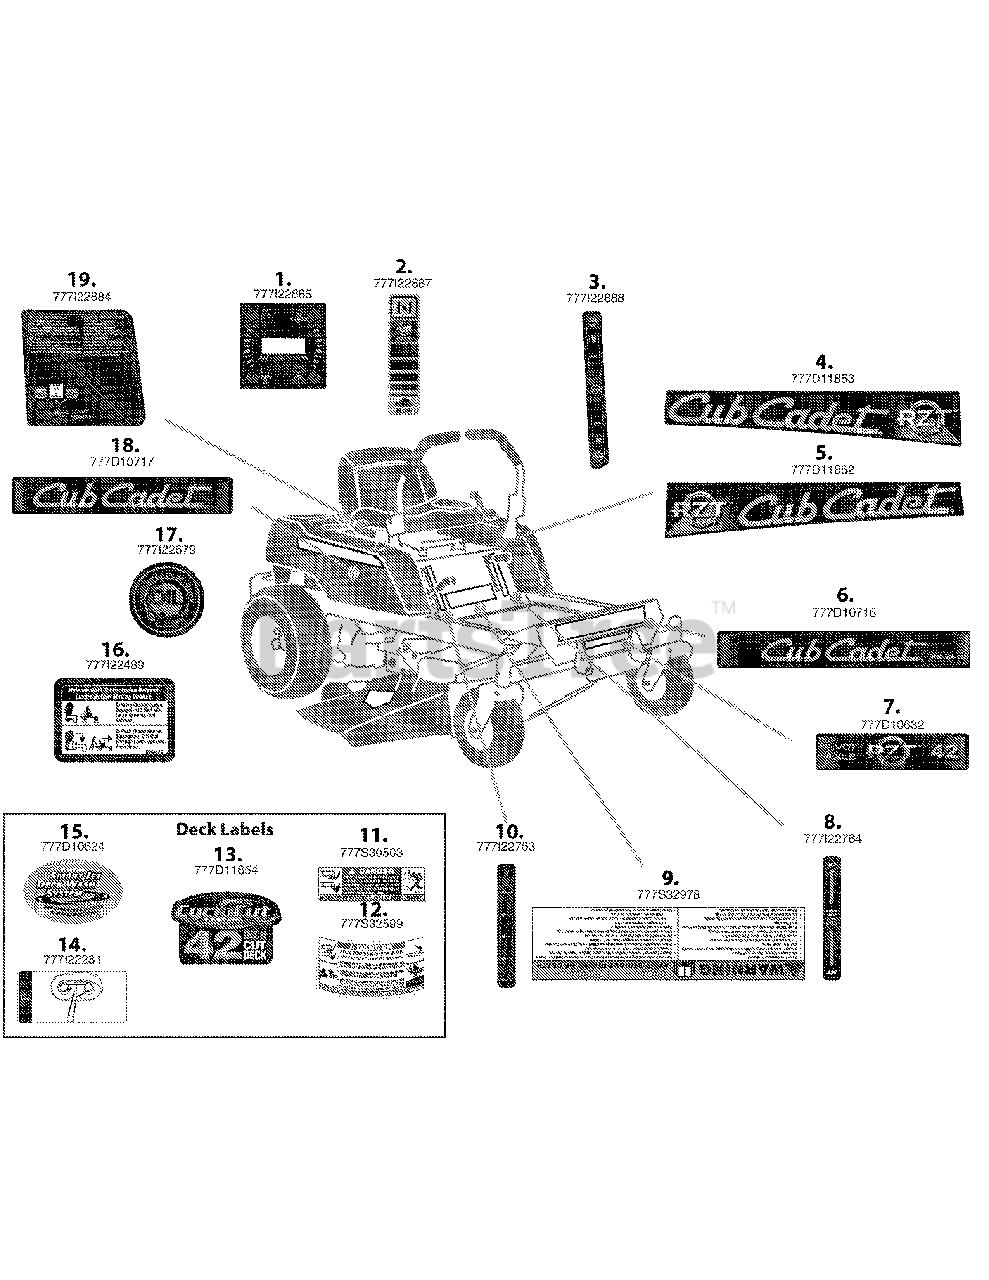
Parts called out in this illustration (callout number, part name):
1	LABEL-HOUR METER LH POD
2	LABEL-THROTT/CHOKE LH POD
3	LABEL-FUEL LEVEL LH POD
4	LABEL-CUB CADET RZT RH POD
5	LABEL-CUB CADET RZT LH POD
6	LABEL-FRONT FRAME CUB CADET
7	LABEL-RZT 42 AXLE PIVOT
8	LABEL-PARK BRAKE
9	LABEL-COMMON WARNING
10	LABEL-HANDLE HEIGHT
11	LABEL-DANGER CHUTE
12	LABEL-RZT DECK WARNG CURVE
13	LABEL-CYCLO CUT 42"
14	LABEL-BELT ROUTE
15	LABEL-RIDER:DECK WASH CUB
16	LABEL-TRNMSN RELEASE
17	LABEL-CHECK ENG OIL
18	LABEL-REAR FRAME CUB CADET
19	LABEL-START INSTR RH POD
